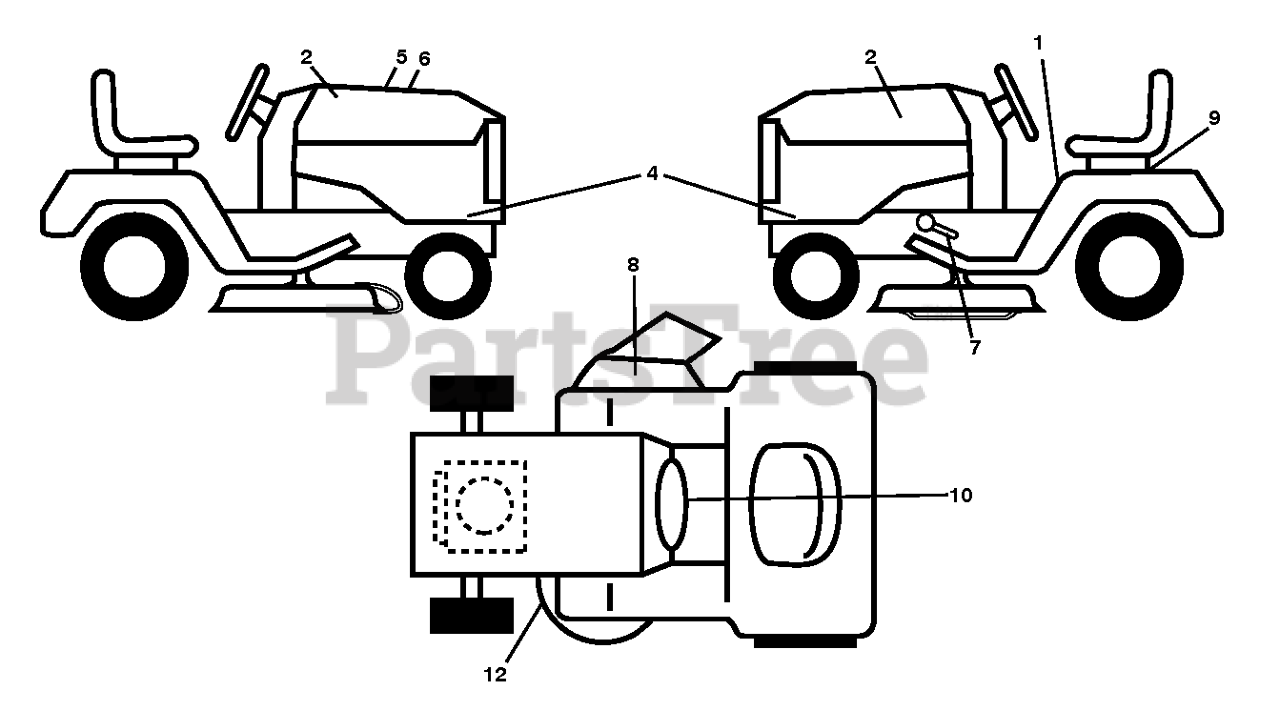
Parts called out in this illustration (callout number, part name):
1	DECAL.FENDER.WARNING.ENGLISH
2	DECAL.BADGE.170MM.TEXTLOGO.
3	DECAL.MOWER.WARN.KEEP.HAND.AWY
4	DECAL HOOD PANEL
5	DECAL.WARNING.CUST.RESP.E85.
6	DECAL.RPL.KW.FR600.TLW.42.K46
7	DECAL.PEDAL.HUSQ.CROWN
9	DECAL BTRY SYMBOLS
10	DECAL, WARNING SPARK ARRESTOR
12	DECAL.V-BELT.SCH.42/46"MEC/ELE
